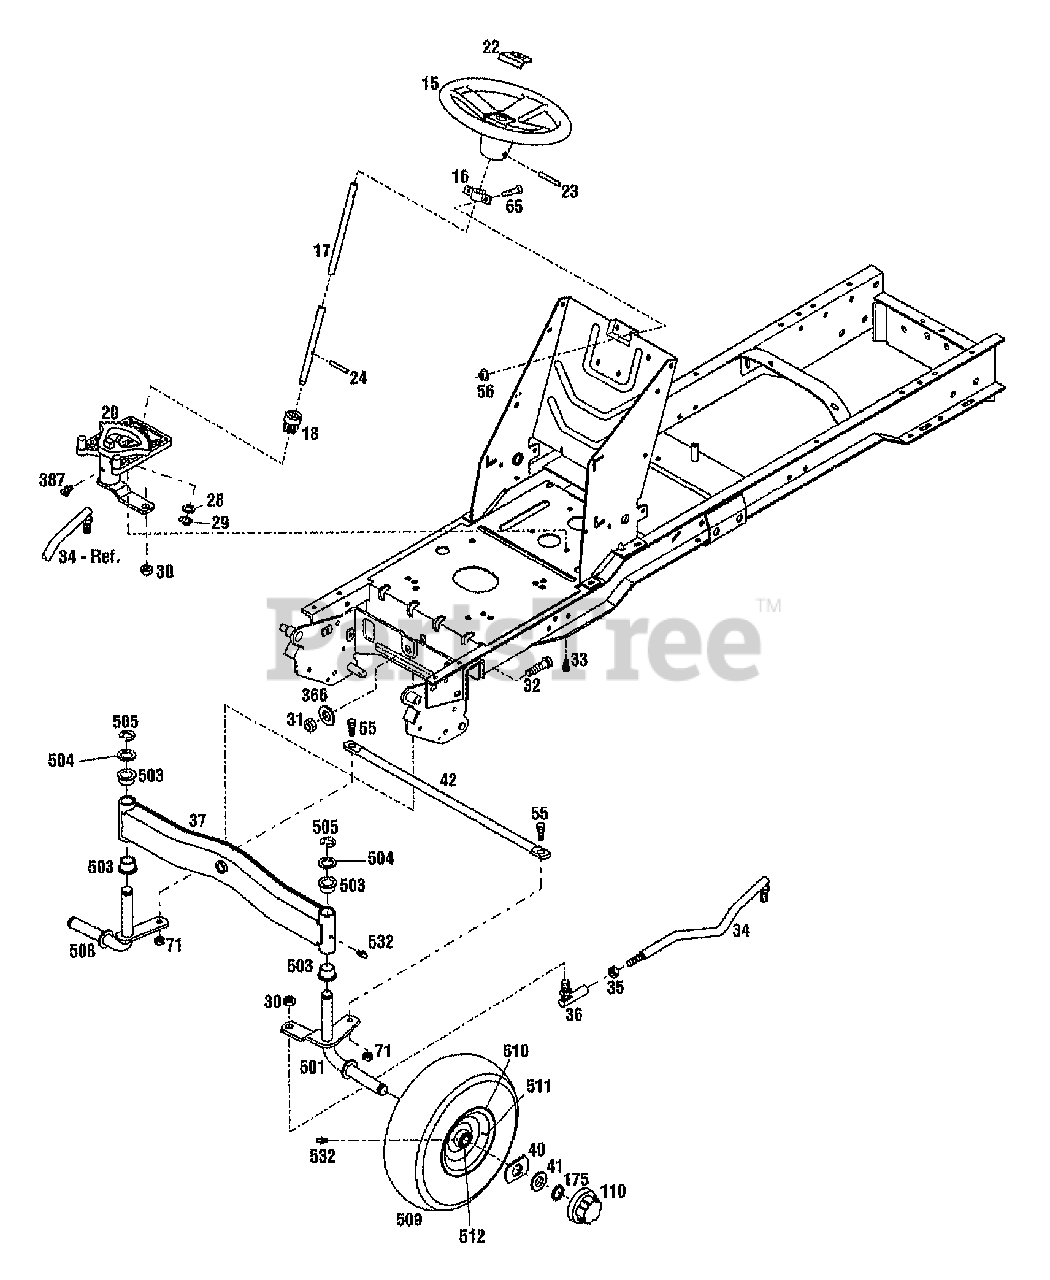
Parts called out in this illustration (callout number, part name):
15	WHEEL-STEERING
16	BEARING
17	SHAFT-STEERING
18	GEAR-PINION
20	ASSM-STEERING GEAR
22	CAP-STEERING
23	PIN-ROLL .25X2.25
24	PIN-ROLL 1/4 X 1-1/4
28	WASHER-1.0X.64X.09
29	RING-RETAINING
30	NUT-HEX/JAM 1/2-20
31	NUT-H/LK 5/8-11
32	SCR-HH
33	SCR-HFLK 5/16-18X.75
34	LINK-DRAG
35	NUT-JAM
36	JOINT-BALL
40	WASHER-SPEC .75X2.50
41	WASHER-1.38 X.765X .06 ZP
55	SCR-SHOULDER
56	NUT-HF/LK 1/4-20 ZP
65	SCR-HH 1/4-20X.625
71	NUT-LOCK
110	CAP-HUB
175	RING-RET."E".577 ID
366	WASHER-1.75X.687X.134 ZP
387	FITTING-GREASE 90 DEGREE
501	ASSM-SPINDLE LH
504	WASHER-1.25X.765X.049
505	RING-HEAVY EXT HD 1.0 ID
508	ASSM-SPINDLE WHEEL RH
509	TIRE 15X6.00-6RS
510	DISC WHEEL
511	STEM-VALVE
512	BEARING-BALL W/SEAL
532	FITTING-GREASE 1/4-28X2.00
